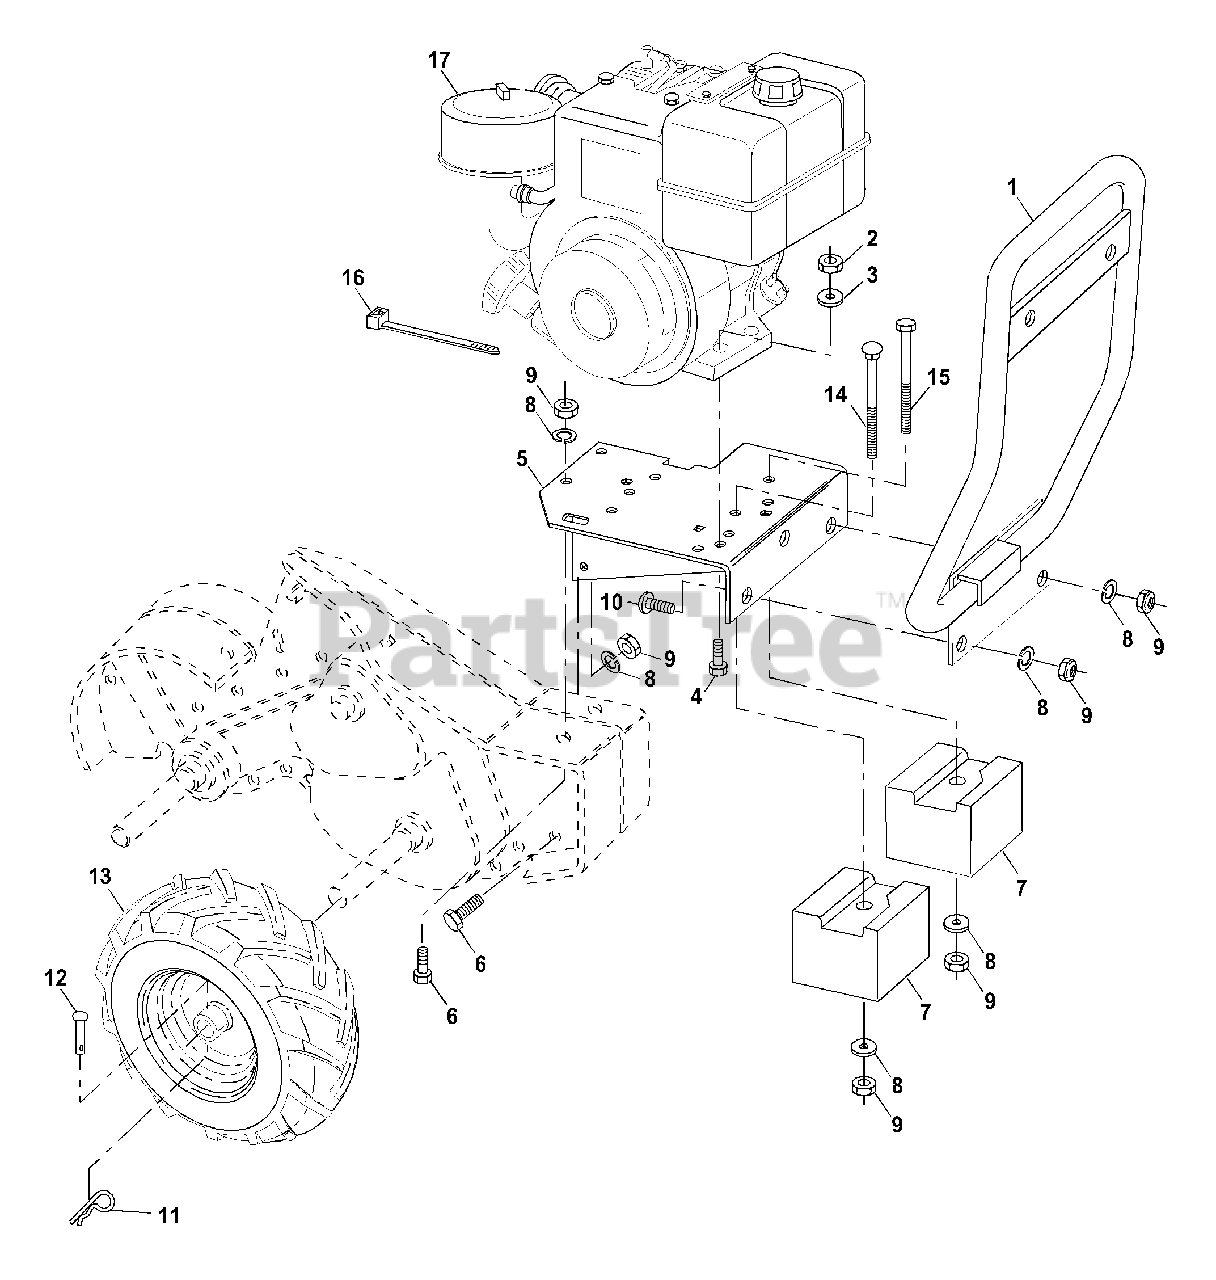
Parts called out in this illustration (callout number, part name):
2	Nut Fin Hex 5/16-18
3	Washer Lock Hvy Hlcl Spr 5/16
4	Bolt, Hex 5/16-18 x 1-3/4
5	Bracket, Engine
6	Bolt, Hex Head 3/8-16 x 1
7	Counter Weight, R.H.
8	Washer, Lock 3/8
9	Nut, Hex 3/8-16
10	Bolt, Carriage 3/8-16 x 1
11	Clip, Hairpin
12	Rivet, Drilled
13	Tire Valve
14	Bolt, Carriage 3/8-16 x 4-1/2
15	Bolt, Hex Head 3/8-16 x 4-1/2
16	Tie, Cable
17	Engine, Briggs & Stratton
